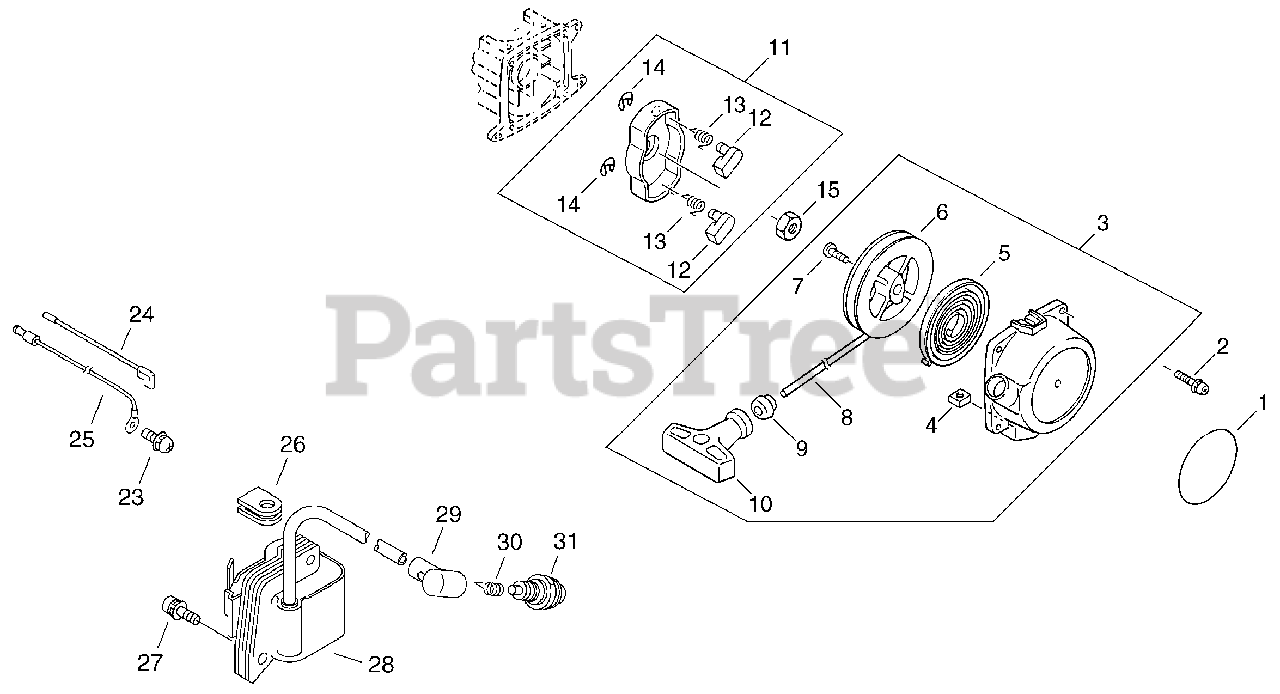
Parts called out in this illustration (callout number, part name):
1	LABEL, RECOIL STARTER
2	BOLT 4×14
3	STARTER ASSY, RECOIL
4	NUT M5
5	SPRING, RECOIL
6	REEL, ROPE
7	SCREW
8	ROPE, STARTER 3×800
9	GUIDE, ROPE
10	GRIP, STARTER
11	PAWL ASSY, STARTER
12	PAWL, STARTER
13	SPRING, RETURN
14	E-RING 4
15	NUT 8×1.25
23	SCREW 5×10
24	LEAD - IGNITION 145 MM
25	LEAD - GROUND
27	BOLT 5×22
28	COIL, IGNITION
29	CAP, SPARK PLUG
30	TERMINAL, SPARK PLUG
31	SPARK PLUG - BPM7A
